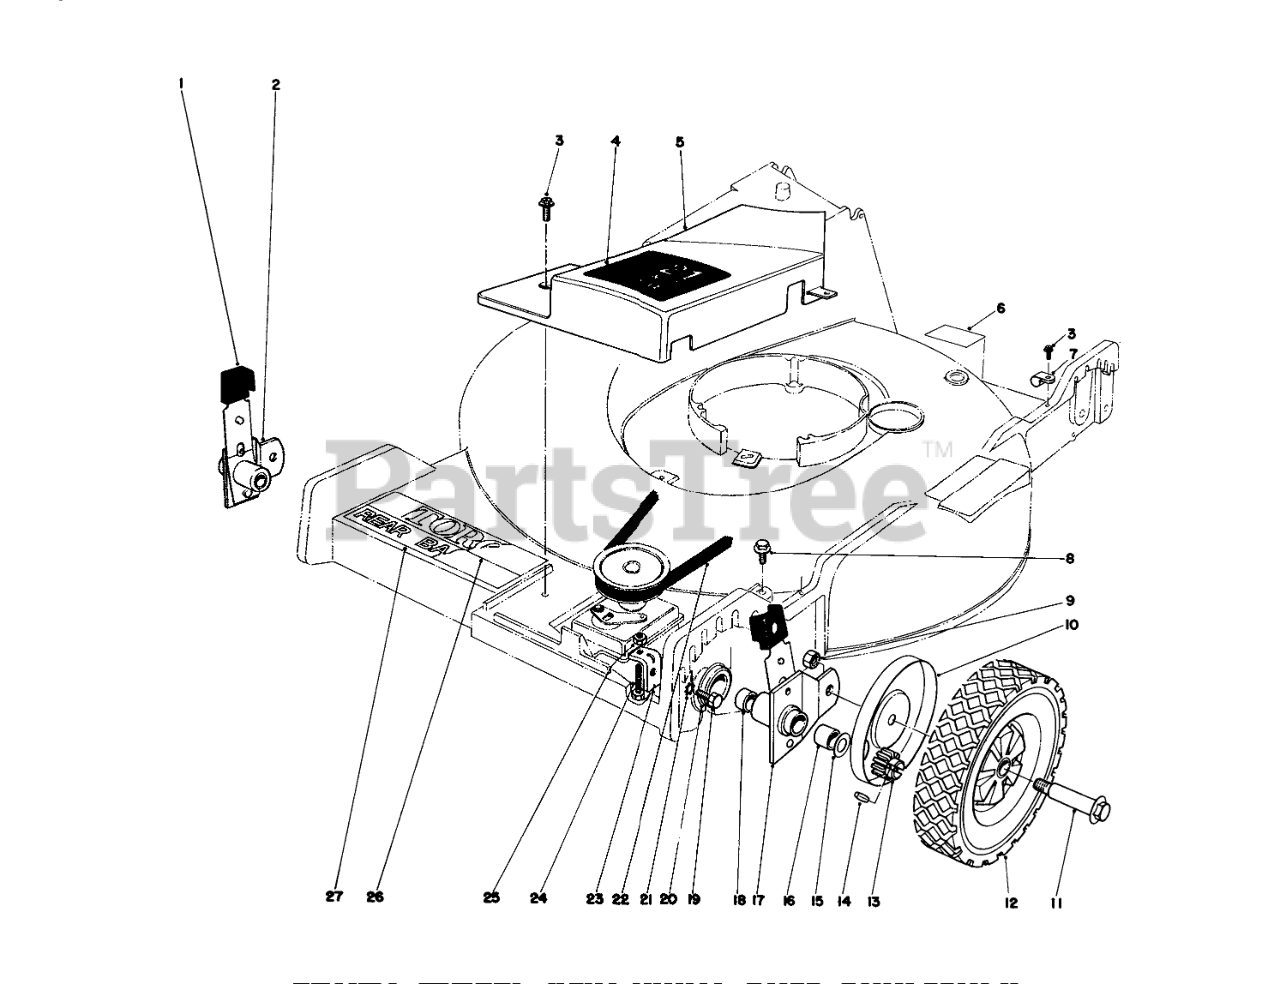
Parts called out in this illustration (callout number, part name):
1	KNOB-ARM
2	Pivot Arm R.H. (Incl. Ref. #16 & 18)
3	SCREW
4	Decal Belt Cover
5	BELT COVER
6	Greasing Sticker
7	CLAMP-NYLON
8	SCREW-HWHTF
9	Nut
10	WHEEL COVER
11	BOLT-WHEEL
12	Wheel & Tire Assembly
13	Pinion
14	PIN-GROOVED
15	WASHER-THRUST
16	Bushing
17	Pivot Arm L.H. (Incl. Ref. #16 & 18)
18	Bushing
19	SCREW-HH
20	END CAP
21	WASHER-LOCK
22	V-Belt
23	Bracket-Gear Box
24	SCREW
25	NUT-LOCK
26	TORO LOGO DECAL
27	DECK DECAL
